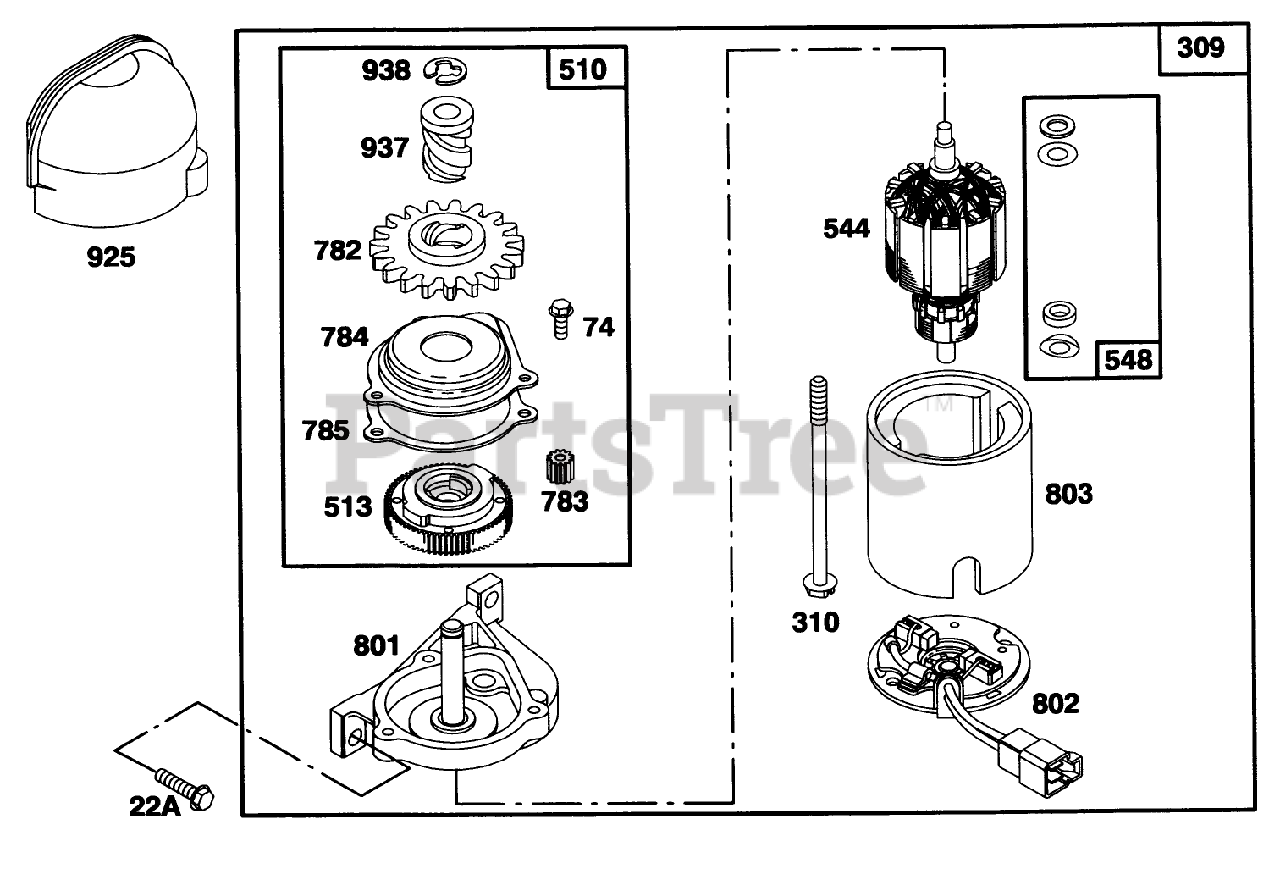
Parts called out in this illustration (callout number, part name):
510	DRIVE SET
513	CLUTCH - STARTER
548	RETAINER - SPRING
782	GEAR - STARTER
925	COVER - STARTER
938	RETAINER - LOCK
